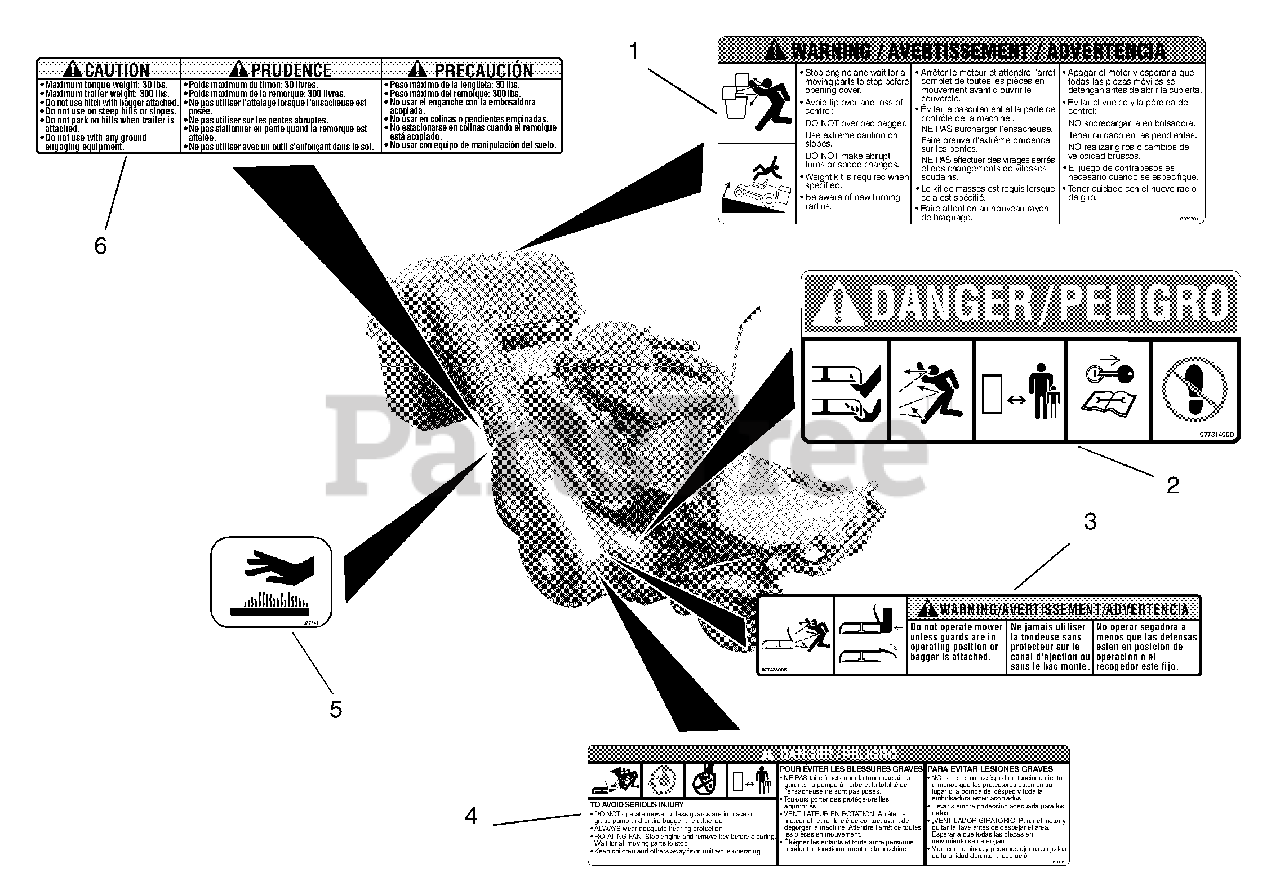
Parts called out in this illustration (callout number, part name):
1	Bagger Cover Decal
2	Mower Pan Danger Decal
3	Warning Decal
4	Grass Pump Caution Decal
5	Decal, Hot Surface
6	Decal, Trailer Hitch
